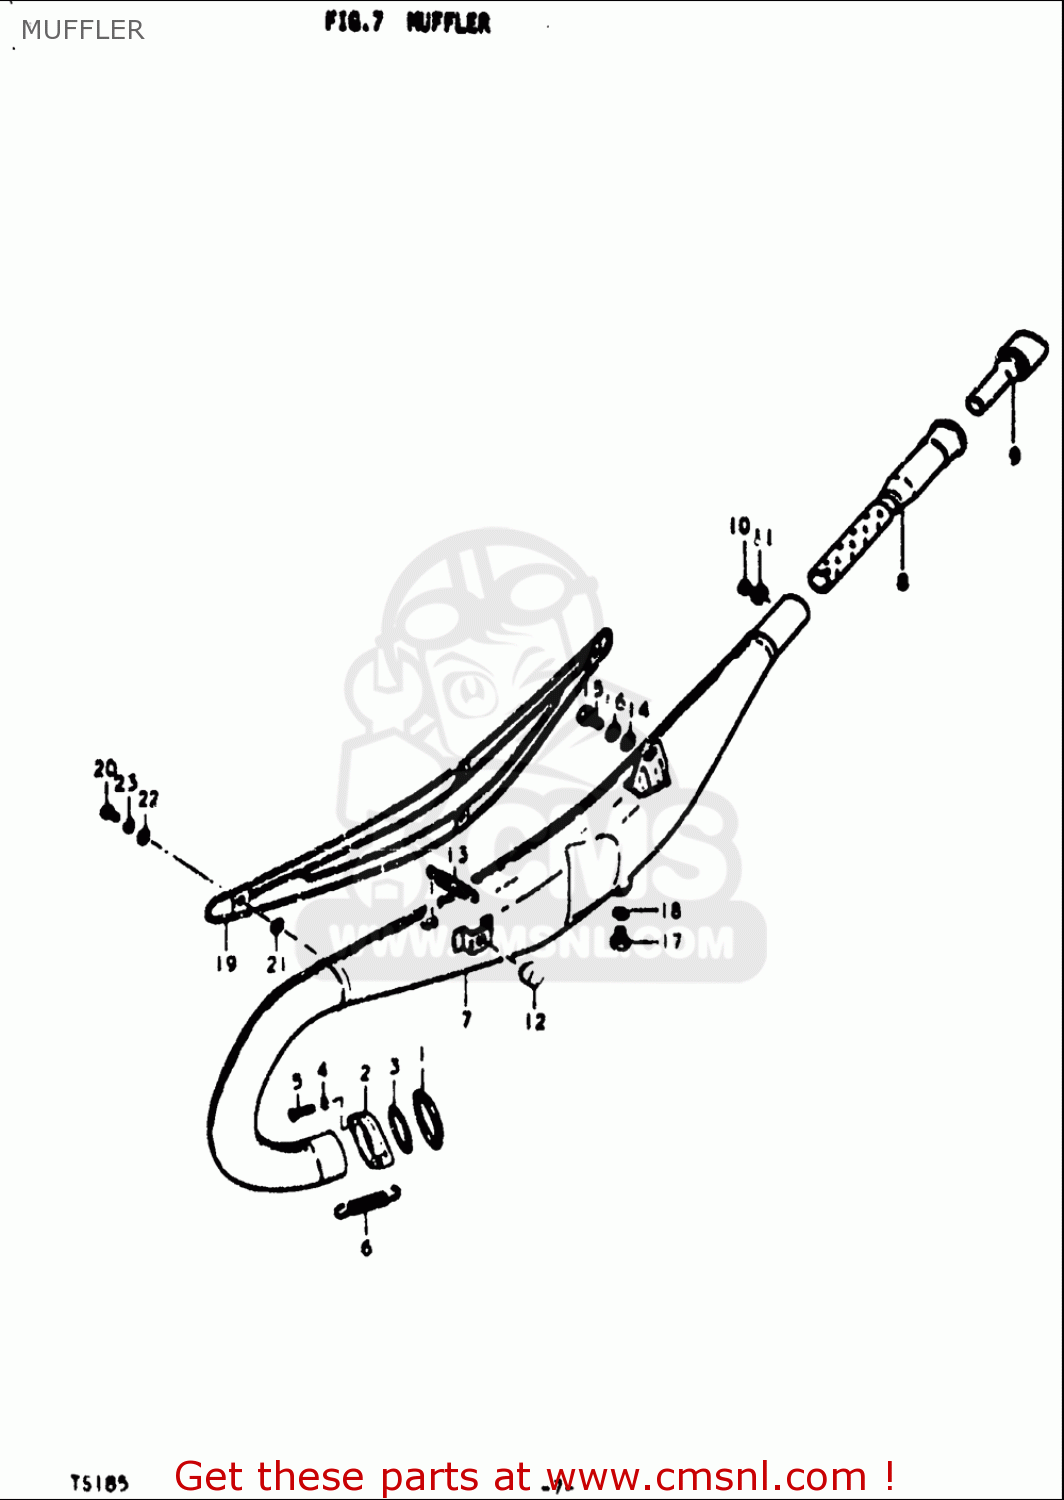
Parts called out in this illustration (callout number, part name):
1	GASKET,EXHAUST PIPE (NAS)
2	CLAMP,EXHAUST PIPE
3	CUSHION,EXHAUST PIPE
4	WASHER,LOCK
5	BOLT
6	SPRING
10	SCREW
11	WASHER,LOCK
12	CUSHION
13	SPRING
14	WASHER(8X14X3)
15	BOLT
16	WASHER(8.5X18X2)
17	BOLT 10X9
18	GASKET(10X14X3.6) (NAS)
20	SCREW
21	GASKET(6.2X12X1.5) (NAS)
22	WASHER
23	WASHER,LOCK
